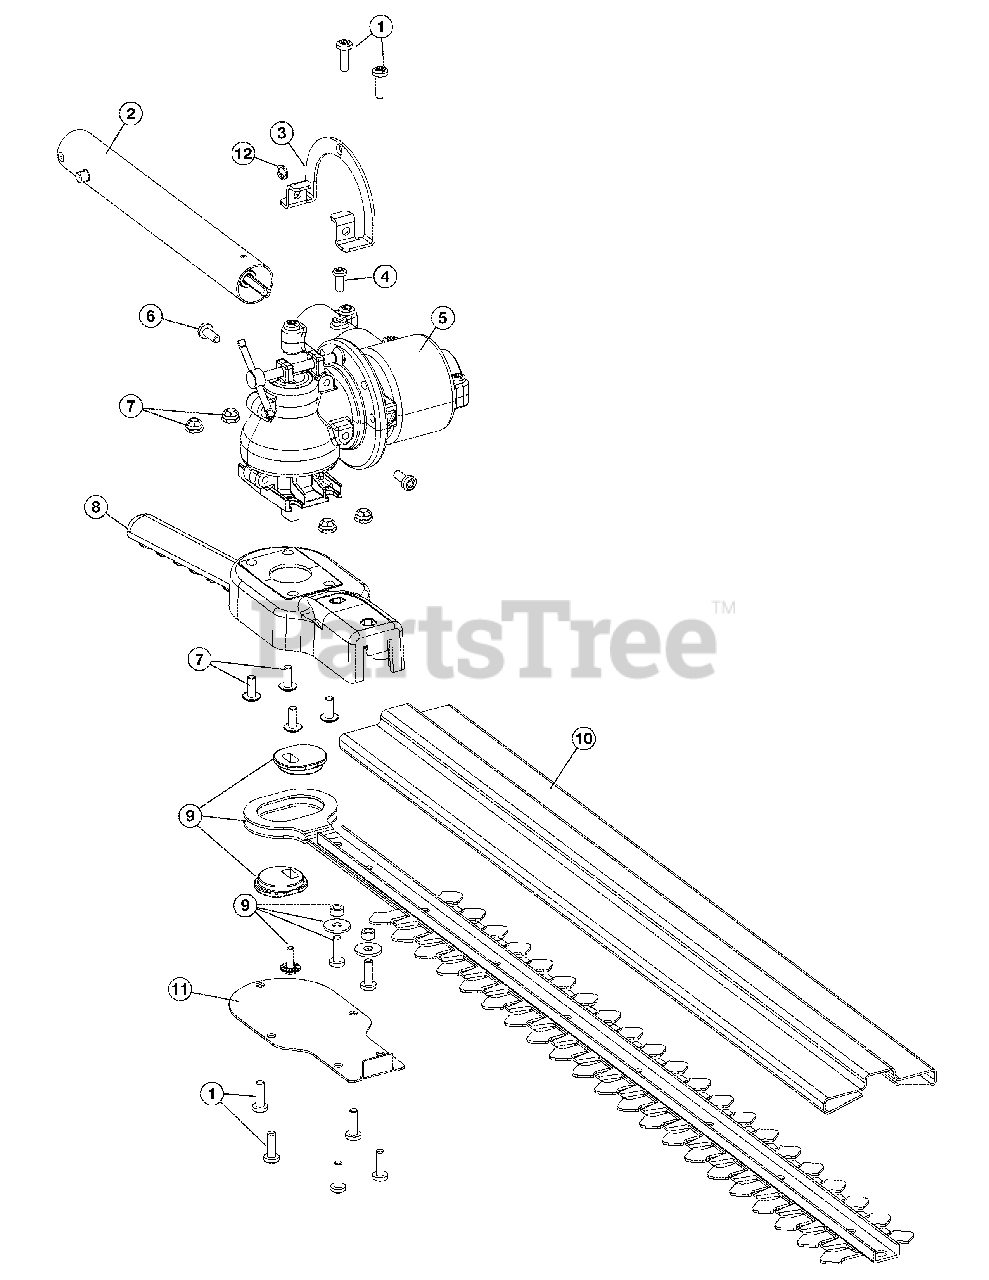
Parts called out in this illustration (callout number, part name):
2	Drive Shaft Housing Assembly
3	Indexing Ring
4	Anti-Rotation Screw
5	Gearbox Assembly (includes 4)
6	Screw
7	Blade Housing Hardware
8	Upper Blade Housing (Includes 7)
9	Blade Assembly
10	Guard
11	Lower Blade Assembly
12	Lock Washer
